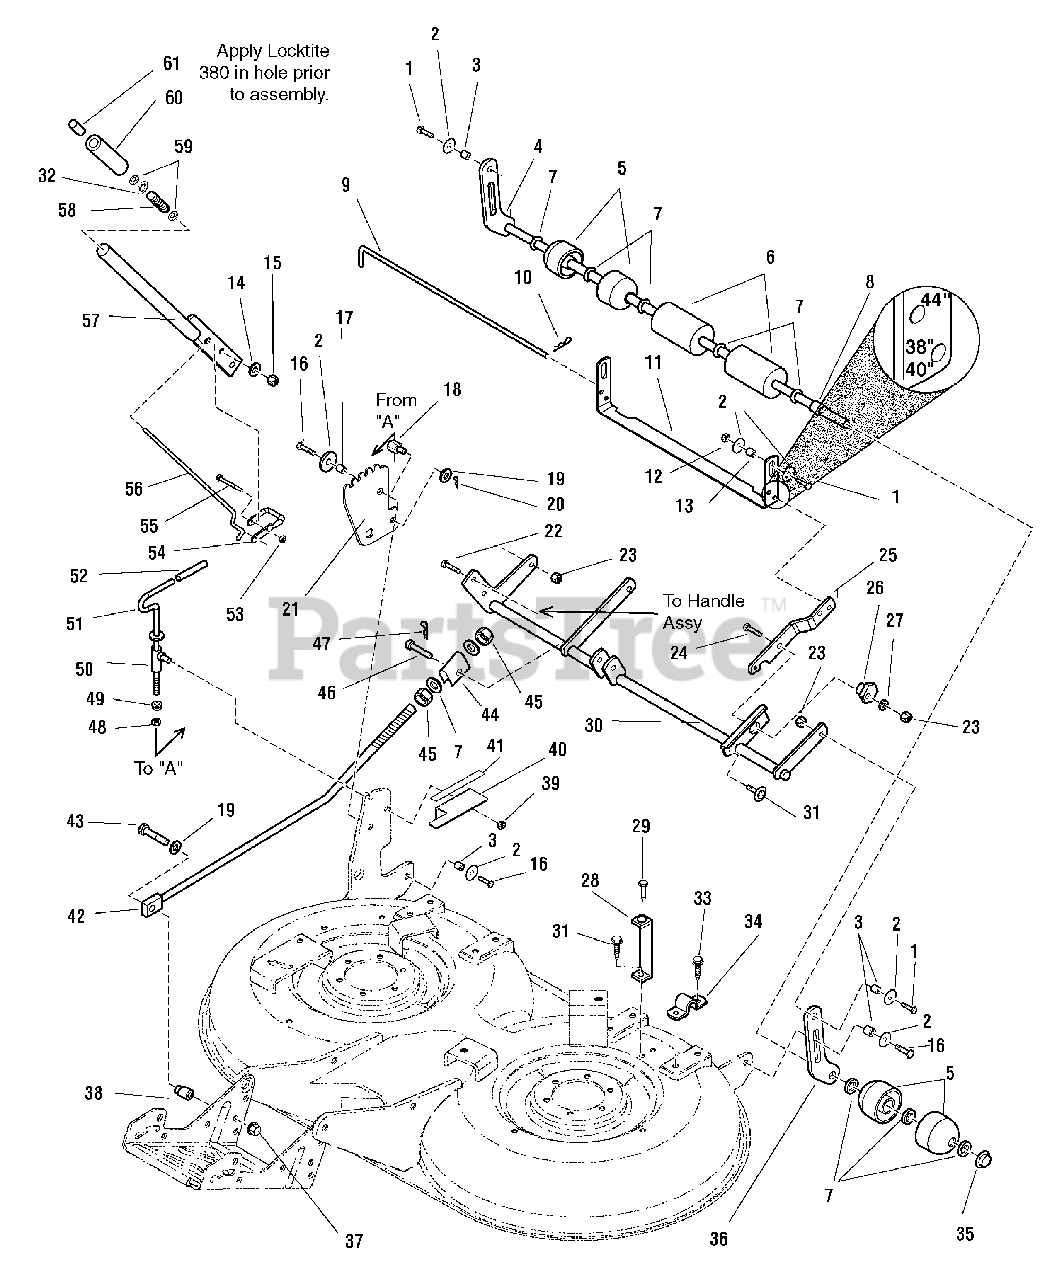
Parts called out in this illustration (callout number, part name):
1	CAPSCREW, Hex Head, 5/16-18 x 1 1/4
2	WASHER, 5/16
4	SHAFT & BAR ASSEMBLY, 40" Roller
7	WASHER, 5/8
9	ROD, Transport
10	CLIP, Hair Pin
11	U-BRACKET
12	NUT, Hex Centerlock, 5/16-18
14	LOCKWASHER, 5/16
15	NUT, Hex, 5/16-18
16	CAPSCREW, Hex Head, 5/16-18 x 1 1/4
18	PIVOT, 3/4 Hex
19	WASHER, 3/8
20	PIN, Cotter
21	BRACKET, Adjusting
22	CARRIAGE BOLT, 5/16-18 x 1
23	NUT, Hex Flange Lock, 5/16-18
24	CARRIAGE BOLT, 5/16-18 x 1 1/4
26	CAM, Eccentric, 1 1/8 Hex
27	WASHER, 5/16
29	FASTNER, Panel
30	SHAFT ASSEMBLY, Rocker
31	CAPSCREW, Taptite Hex Washer Head, 5/16-18 x 1
32	PUSH NUT, 1/4
33	CAPSCREW, Taptite Hex Washer Head, 5/16-18 x 3/4
34	STRAP, Roller Support
35	NUT, Push 5/8
36	BAR, Roller
37	NUT, Hex TopLock Spiral Lock Flange, 3/8-16
39	NUT, Hex Centerlock, 3/8-16
40	BRACKET, Height of Cut
41	DECAL, Height of Cut
42	ROD, Adjustment
43	CAPSCREW, Hex Head, 3/8-16 x 1-3/4
44	TRUNNION, Rod
45	NUT, Hex, 5/8-11
46	PIN
47	CLIP, Hair Pin
48	NUT, Hex Jam, 3/8-16
49	NUT, Hex Flange, 3/8-16
50	GUIDE ASSEMBLY, Adjustment Rod
51	ROD & WASHER ASSEMBLY, Adjust Handle
52	GRIP, Black Vinyl For Rod
53	NUT, Hex Lock Esna Light, 1/4-20
54	LATCH, 5/16 WIRE
55	CAPSCREW, Hex Head, 1/4-20 x 2 1/4
57	HANDLE ASSEMBLY, Lift
58	SPRING, Compression
59	WASHER, 5/16
60	GRIP, Black Soft for Rod
